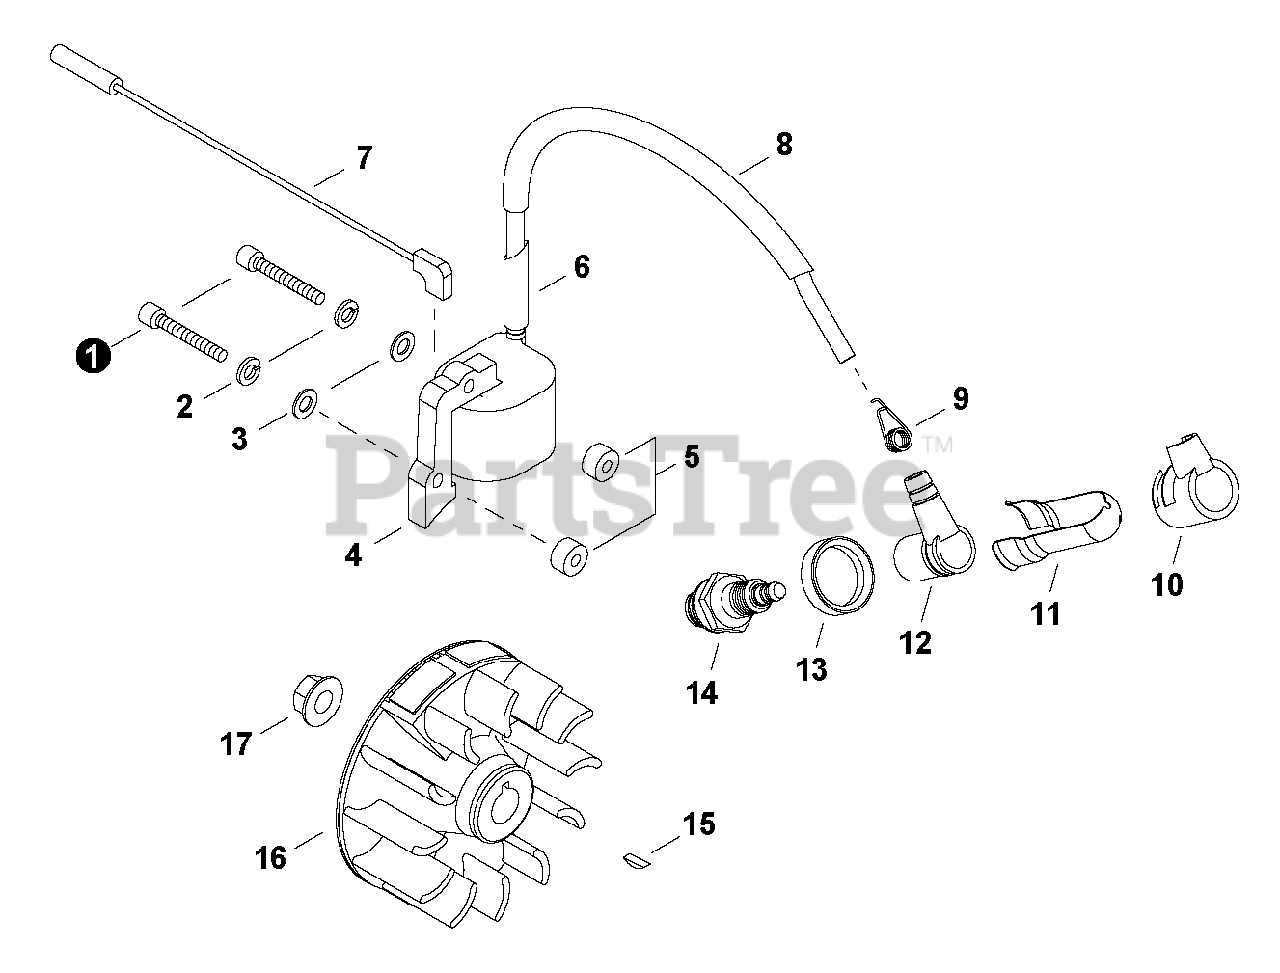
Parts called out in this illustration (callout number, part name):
1	Bolt 4x30
2	Washer, Spring 4mm
3	Washer 4mm
4	Coil, Ignition
5	Insulator 4
6	Sleeve, Insulator
7	Lead, Ground
9	Terminal, Spark Plug
10	Cover, Cap
12	Cap, Spark Plug
13	Seal, Spark Plug
14	Plug, Spark Ngk BMR6A
15	Key, Woodruff 3x10
16	Flywheel
17	Nut, Crankshaft M8
